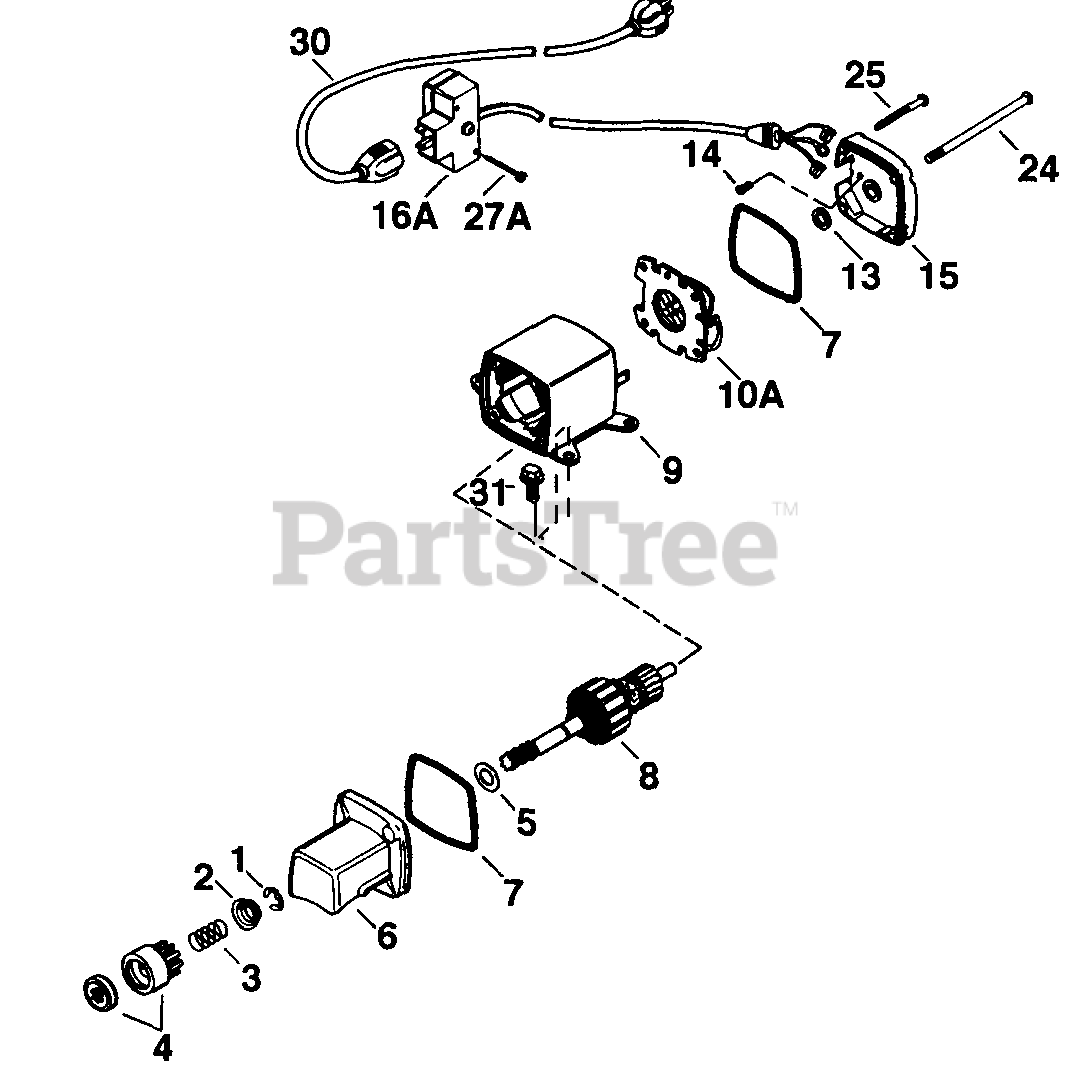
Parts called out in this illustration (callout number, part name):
1	Retainer Ring
2	Spring Retainer
3	Anti-drift Spring
4	Nut & Gear
5	Thrust Washer
6	Drive End Cap Ass'y.
9	Housing Ass'y.
10A	Brush & Spring Card Ass'y.
13	Thrust Washer
14	Ground Screw
15	Commutator End Cap Ass'y.
16A	Switch Box Ass'y.
24	Case Bolt
25	Grounding Screw
27A	Screw, 6-32 x 2-1/2"
30	Extension Cord (10'6")
31	Screw, Torx T-30, 1/4-20 x 23/32"
